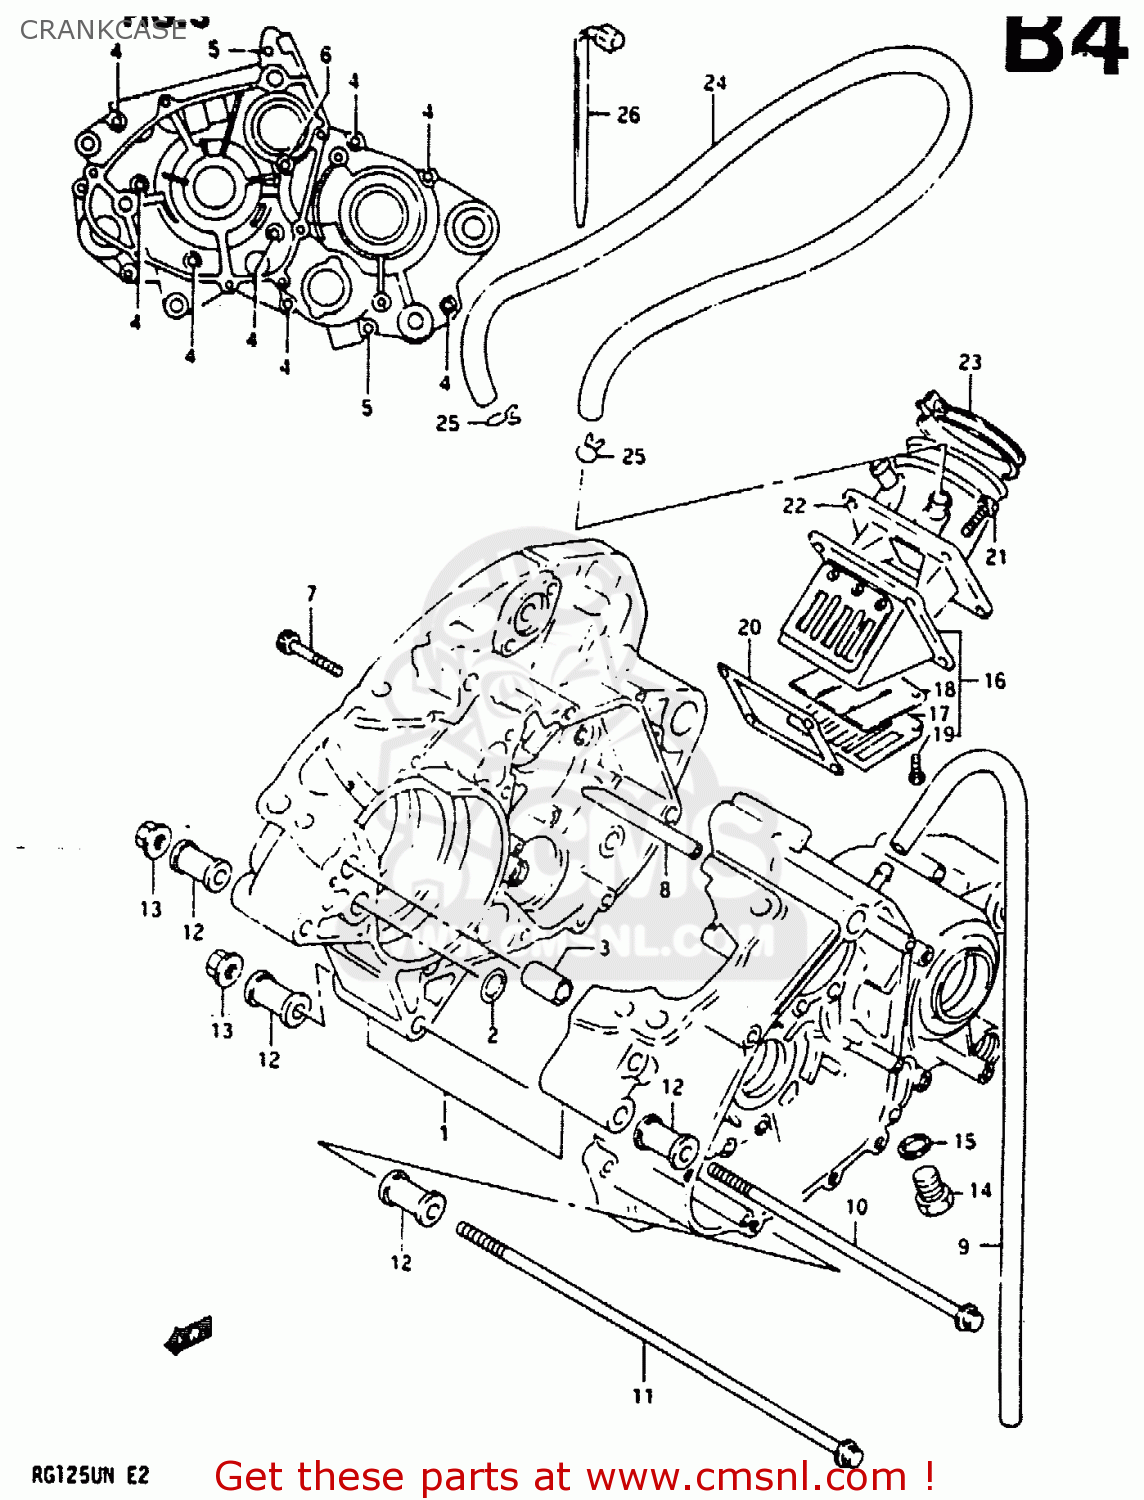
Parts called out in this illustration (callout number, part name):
1	CRANKCASE SET
2	O RING(D:1.9,ID:15.8)
3	PIN(10.4X13X22)
4	BOLT
5	BOLT
6	SCREW, CRANKCASE
7	BOLT
8	PIPE,BREATHER
9	HOSE
10	BOLT(8X175)
11	BOLT(8X265)
12	SPACER, ENGINE MOUNTING
13	NUT
14	PLUG, OIL DRAIN
15	GASKET(14X19.2X2) (NAS)
16	VALVE ASSY,REED
17	STOPPER,REED VALVE
18	VALVE,REED
19	SCREW,REED VALVE
20	GASKET, REED VALVE (NA)
21	BOLT
22	PIPE,INTAKE
23	CLAMP
24	HOSE, INTERFERENCE
25	CLIP
26	CLAMP(L:165)
